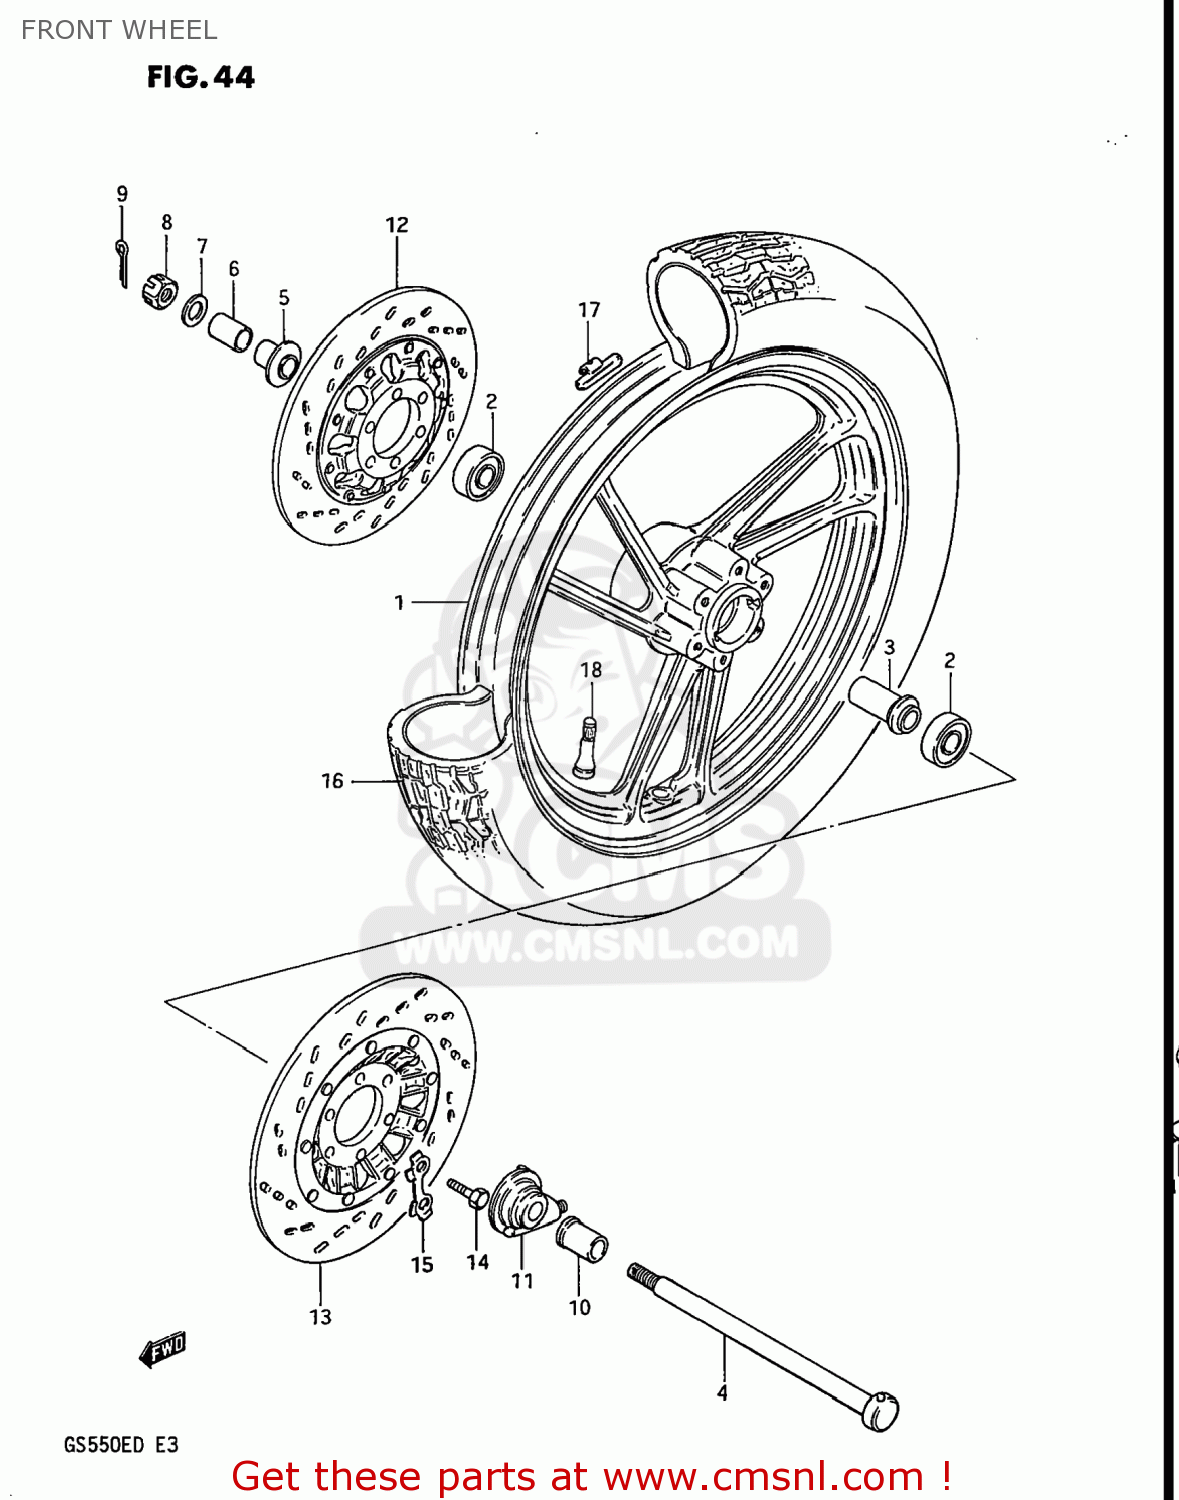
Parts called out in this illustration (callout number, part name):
1	WHEEL,FRONT
2	BEARING
3	SPACER,FR HUB BEARING
4	AXLE,FR
5	SPACER,FR AXLE,R
6	SPACER,FR AXLE,R
7	WASHER
8	NUT 12MM
9	COTTER PIN
10	SPACER,FR AXLE,L
11	BOX ASSEMBLY,SPEEDOMETER GEAR
12	DISC,BRAKE,RIGHT
13	DISC,BRAKE,LEFT
14	BOLT(8X30)
15	WASHER
16	TIRE,FRONT
17	BALANCER,WHEEL
18	VALVE,TIRE
